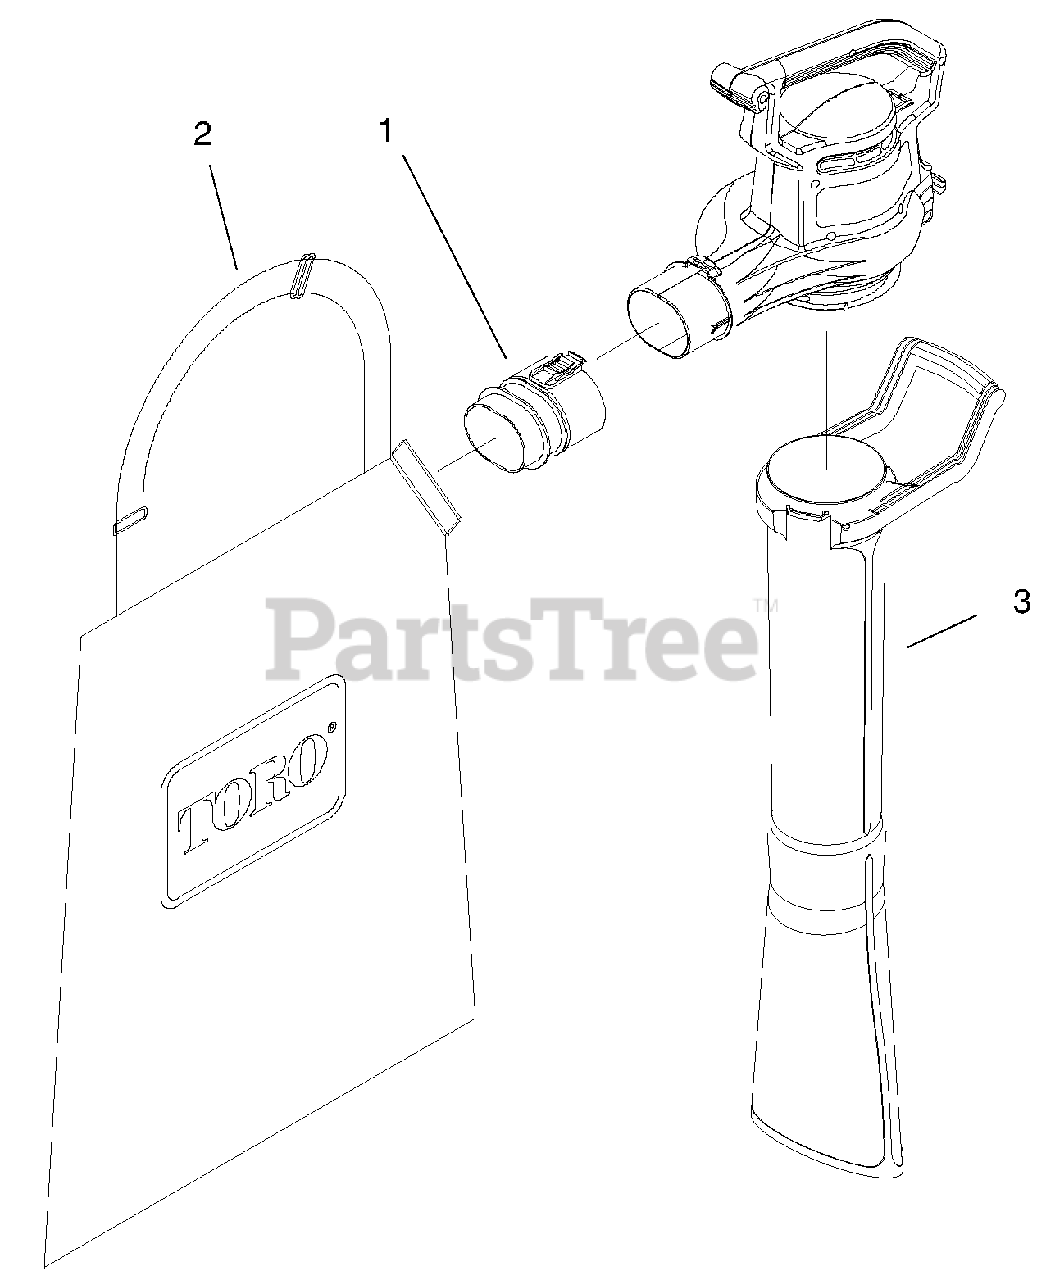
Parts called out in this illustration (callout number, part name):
1	Tube-Bag Inlet
2	Bag
3	Tube-Vac
